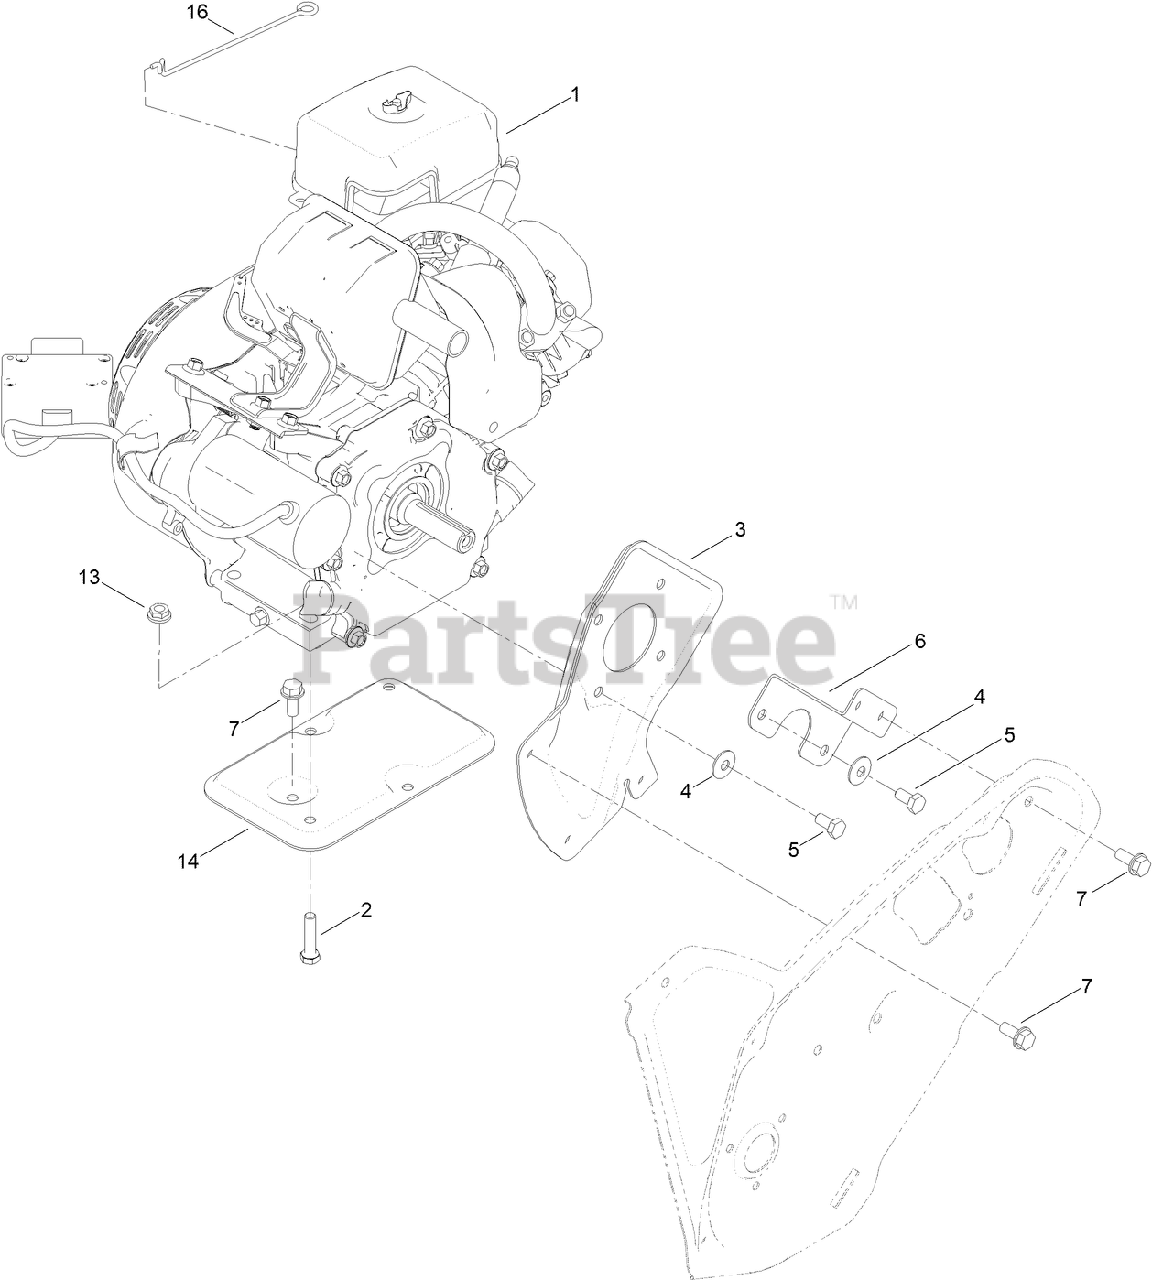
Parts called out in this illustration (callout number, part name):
1	ENGINE-170FDS-2
2	SCREW-HH
3	PLATE-ENGINE, PTO
4	WASHER-BELLEVILLE
5	SCREW-HH
6	SUPPORT-ENGINE, SIDE
7	SCREW-THD ROLL, HWH
13	NUT-HF
14	SUPPORT-ENGINE
